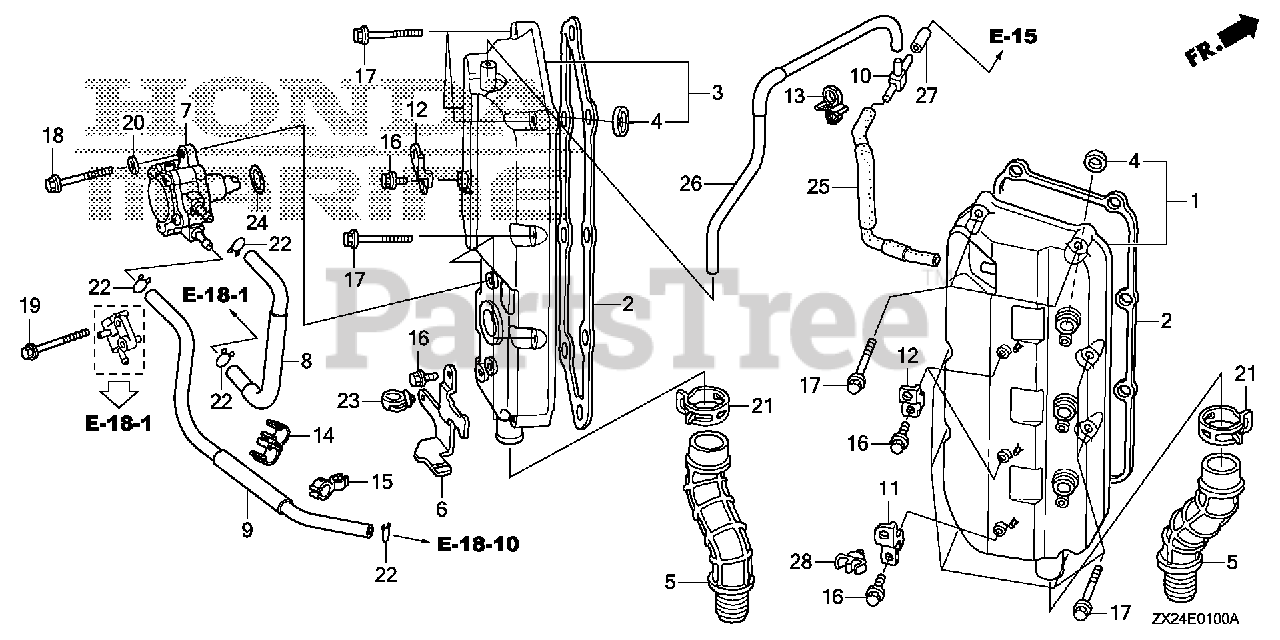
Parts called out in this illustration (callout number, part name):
1	COVER, R. CYLINDER HEAD *NH8* (DARK GRAY)
2	GASKET, HEAD COVER
3	COVER, L. CYLINDER HEAD *NH8* (DARK GRAY)
4	SEAL, SPARK PLUG TUBE (NOK)
5	TUBE, OIL
6	BRACKET, SOLENOID VALVE
7	PUMP ASSY., FUEL (MSDS)
8	TUBE, FUEL (C)
9	TUBE G, FUEL
11	BRACKET, CLIP B
12	BRACKET C, HARNESS CLIP
13	CLIP A, WIRE
14	CLIP, SENSOR HOSE
15	CLIP, SHIFT WIRE
16	BOLT, FLANGE (6X14) (CT200)
17	BOLT, FLANGE (6X35)
18	BOLT, FLANGE (8X32)
19	BOLT, FLANGE (8X45)
20	WASHER, PLAIN (8MM)
21	CLAMP, TUBE (D32.5)
22	CLIP, TUBE (B12)
23	CLIP, HARNESS
24	O-RING (37X2.4) (ARAI)
25	TUBE A, BREATHER
26	TUBE B, BREATHER
27	TUBE C, BREATHER
28	CLIP D, WASHER TUBE
